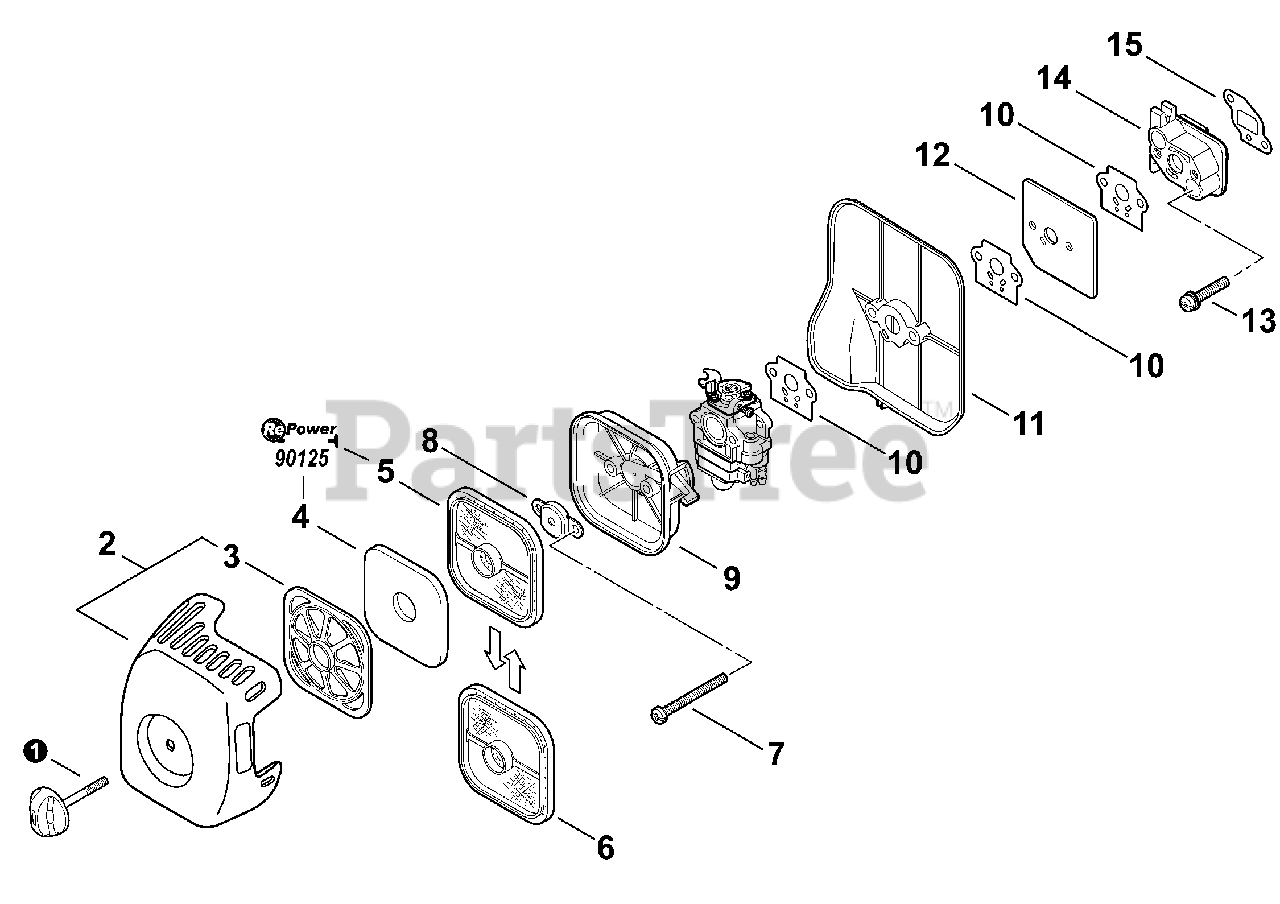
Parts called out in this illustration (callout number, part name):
1	THUMBSCREW
2	AIR CLEANER COVER KIT
3	RETAINER, PRE-FILTER
4	PRE-FILTER - FOAM
5	FILTER, AIR - DOUBLE LAYER
6	FILTER, AIR - SINGLE LAYER
7	SCREW 5×70
8	PLATE, PREVENT
9	CASE, AIR CLEANER - BLACK
10	GASKET, INTAKE
11	PLATE, INSULATOR
12	PLATE, INSULATOR
13	SCREW - 5×30
14	INSULATOR
15	GASKET, INTAKE
